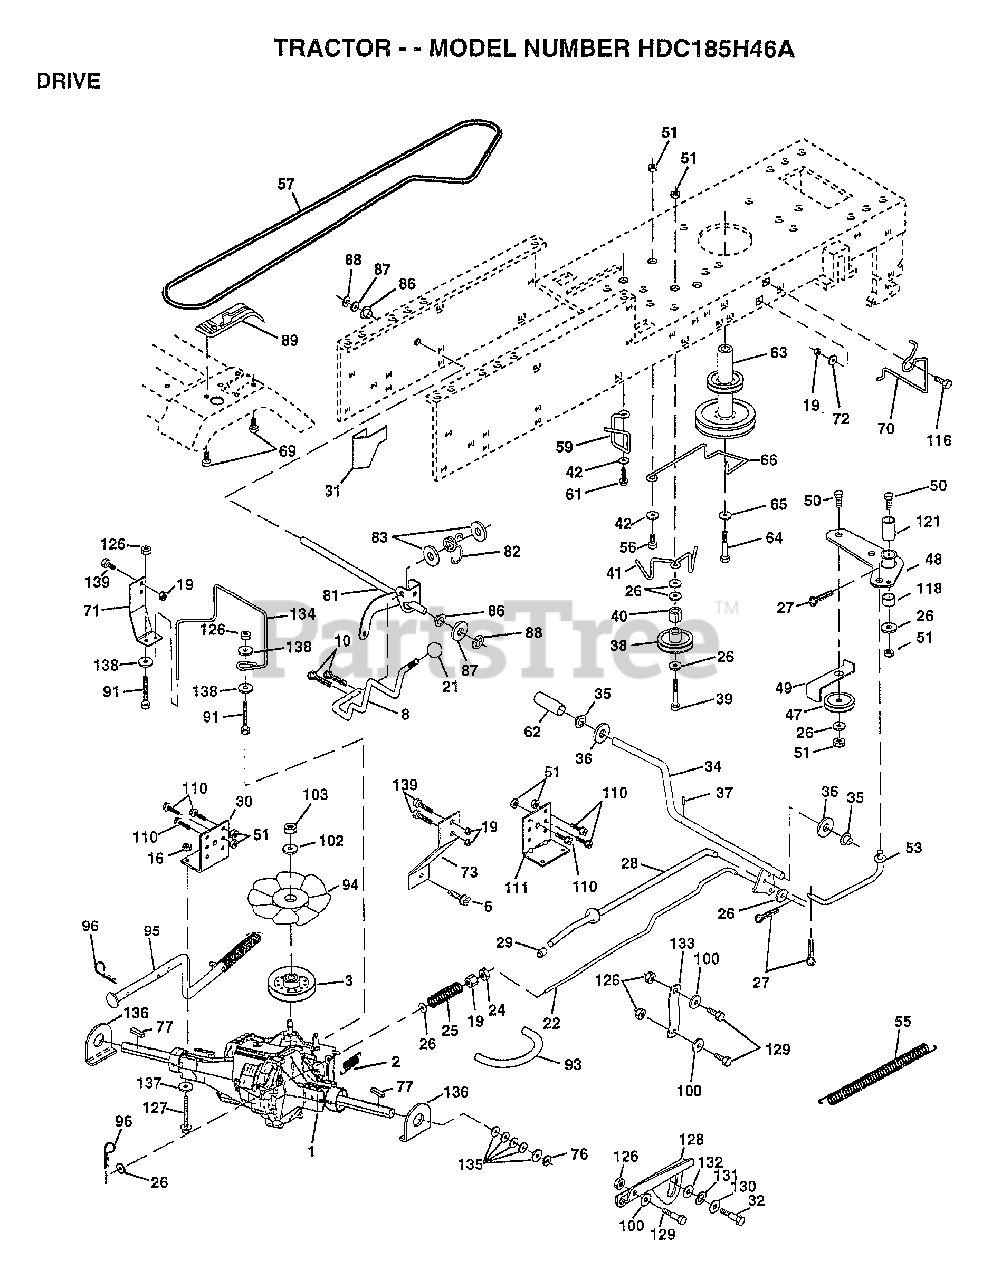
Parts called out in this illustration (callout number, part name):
2	SPRING RET BRAKE
3	PULLEY.TRANSAXLE
6	SCREW
8	ROD SHIFT FEND YT
10	PIN COTTER 1/8
16	NUT
19	NUT
21	KNOB T (1/2-HOLE)
22	BRAKE.ROD.HYDRO.
24	NUT
25	SPRING ROD LT
26	WASHER
27	COTTER PIN
28	ROD.BRAKE.PARK.LT
29	PLUNGER CAP T
30	BRKT TRANS LH
31	KEEPER BELT LH
32	BOLT
34	SHAFT ASM-PEDAL F
35	NYLON BEARING
36	WASHER LT
38	PULLEY.IDLER.FLAT
39	BOLT
40	SPACER T
42	WASHER
48	BELLCRANK ASM
49	RETAIN BELT
53	"LINK, CLUTCH T"
55	"SPRING, RETURN LT"
59	KEEPER BELT CNTSP
61	SCREW
62	PEDAL COVER T
63	PULLEY.ENGINE
64	BOLT
65	LOCKWASHER
66	KEEPER-BELT
69	SCREW HEXWSH H-L
70	"GUIDE.BELT,RH ENG"
71	STRAP.TORQUE.LH.HYDRO
72	WASHER
73	STRAP.TORQUE.RH.HYDRO
76	E RING HYT
77	SQ KEY STD
81	SHAFT ASM. CROSS HYDRO 20" TIRES
82	"SPRING,TORSION"
83	WASHER
86	BUSHING
87	WASHER D
88	KLIP RING
93	"LINE FUEL HYD 4"""
94	"FAN 7"" HYDRO"
95	CONTROL.ASM.BYPAS
96	RETAINER M
100	WASHER M
102	WASHER BELLEVILLE
111	BRKT TRANS RH
116	BOLT RDHD 3/8-16
118	SPACER-BELLCRANK
121	NYLINER-CLUTCHING
127	BOLT FIN HEX 5/16
128	BRKT NEUTRAL ADJ
129	"BOLT,SHOULDER"
130	WASHER
131	LOCKWASHER
132	WASHER
134	"KEEPER BELT,RH"
135	WASHER
136	WASHER AXLE HYDRO
137	WASHER
138	WASHER
139	BOLT
